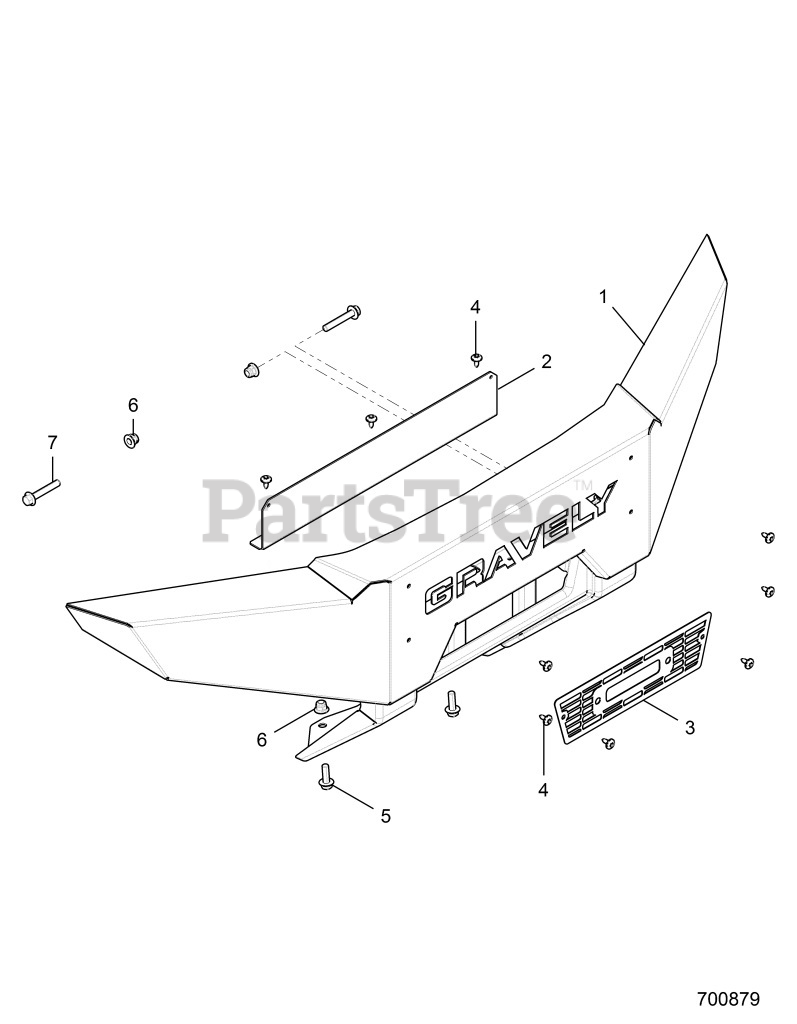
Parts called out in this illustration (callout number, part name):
1	WELD-BUMPER,FRONT,ARIENS,M BLK
2	PLATE, GRAVELY RED
3	SCREEN-BUMPER,BLK
4	SCR-M6X1X16 TR/TX-M
5	SCR-HXFL-M10X1.25X30 8.8 ZOD
6	NUT-M10X1.25,FLG,NYLOC-OLIVE D
7	BOLT-M10X1.25X60,HXFLG-OLIVE D
